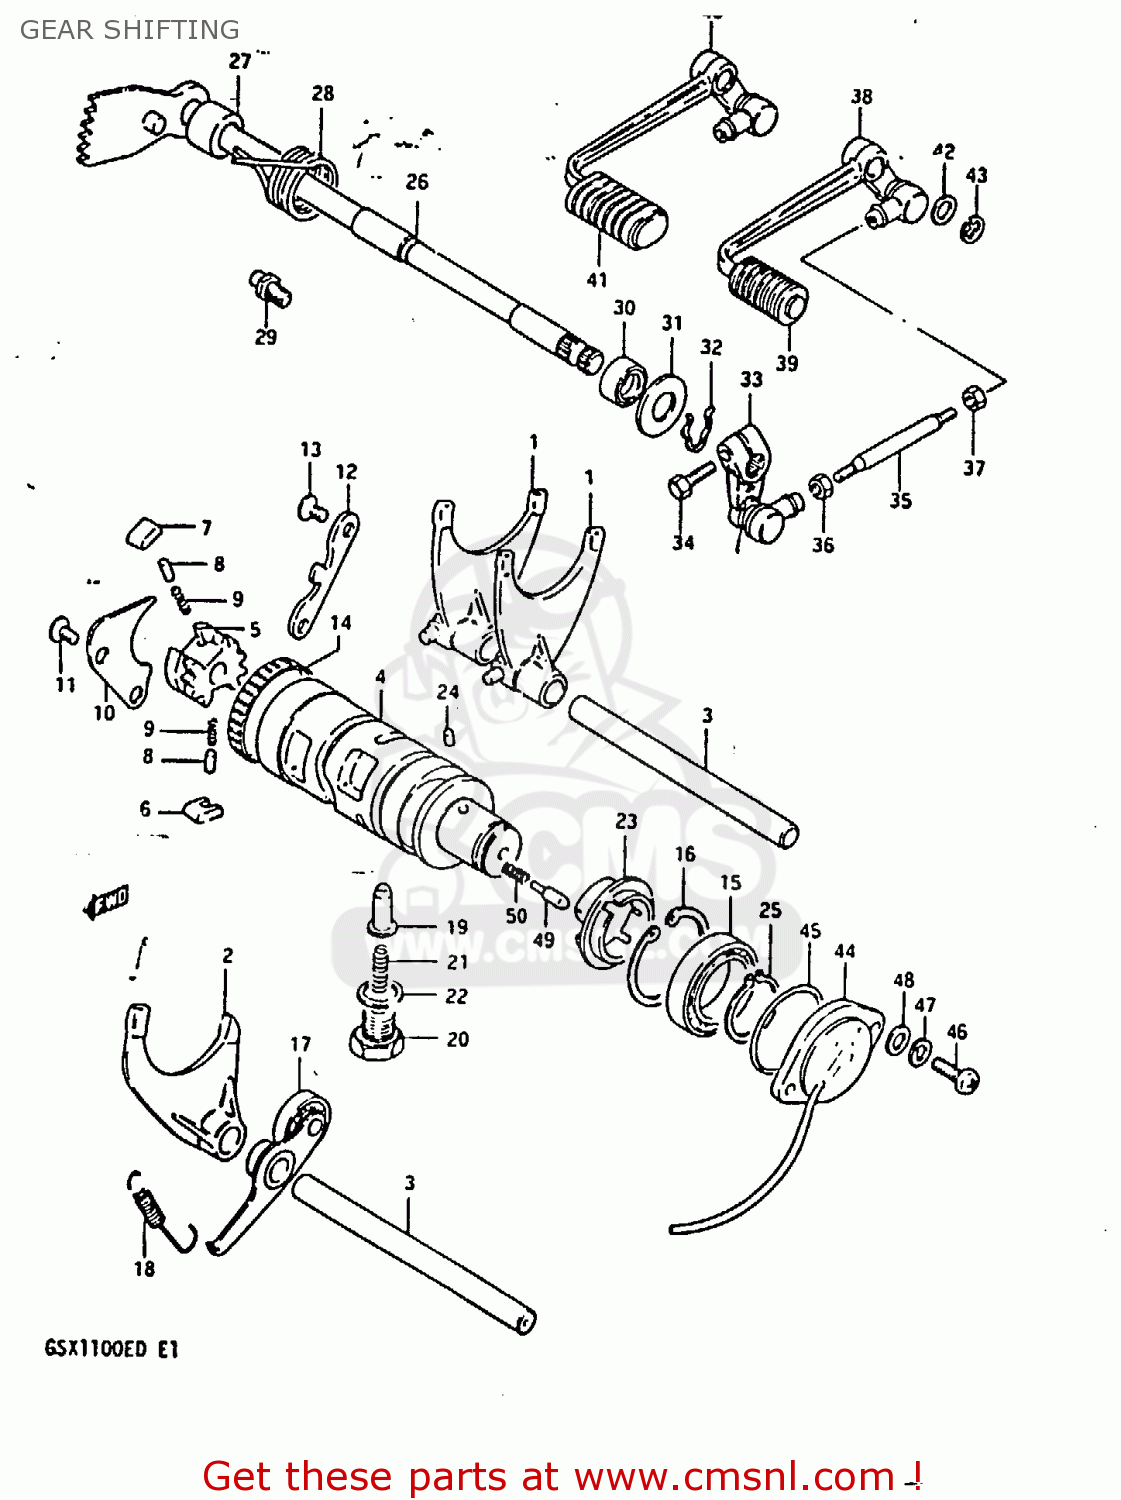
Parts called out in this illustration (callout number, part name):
1	FORK,GEAR SHIFT NO.1
2	FORK,GEAR SHIFT NO.2
3	SHAFT,GEAR SHIFT FORK
4	CAM,GEAR SHIFT
5	RETAINER,GEAR SHIFT CAM
6	PAWL,GEAR SHIFT NO.1
7	PAWL,GEAR SHIFT NO.2
8	PIN(5X8)
9	SPRING
10	LIFTER,GEAR SHIFT PAWL
11	SCREW
12	GUIDE,GEAR SHIFT CAM
13	SCREW
14	BEARING(43X49X12)
15	BALL BEARING
16	CIRCLIP,42MM
17	STOPPER,GEAR SHIFTING
18	SPRING
19	STOPPER,GEAR SHIFT CAM NO.2
20	HOLDER,GEAR SHIFT CAM STOP SPR
21	SPRING
22	GASKET(14X19.2X2) (NAS)
23	PLATE,GEAR SHIFT CAM STOPPER
24	PIN 4X6
25	CIRCLIP,25MM
26	SHAFT,GEAR SHIFT
27	SPACER(12X20X15.3)
28	SPRING
29	STOPPER,GEAR SHIFT CAM
30	OIL SEAL
31	WASHER (12.5X27X1.6)
32	SPRING,RETAINER
33	ARM,GEAR SHIFT LINK
34	BOLT
35	ROD,GEAR SHIFT LINK
36	NUT
37	NUT
38	LEVER ASSEMBLY,GEAR SHIFTING
39	RUBBER,GEAR SHIFT PEDAL
40	LEVER ASSEMBLY,GEAR SHIFTING
41	RUBBER,PEDAL
42	WASHER(12.5X20X1)
43	CIRCLIP
44	BASE ASSEMBLY,NEUTRAL SWITCH TERMINAL
45	O RING(D:2.4,ID:36.5)
46	SCREW
47	LOCK WASHER
48	WASHER
49	PIN(5X15.5)
50	SPRING
